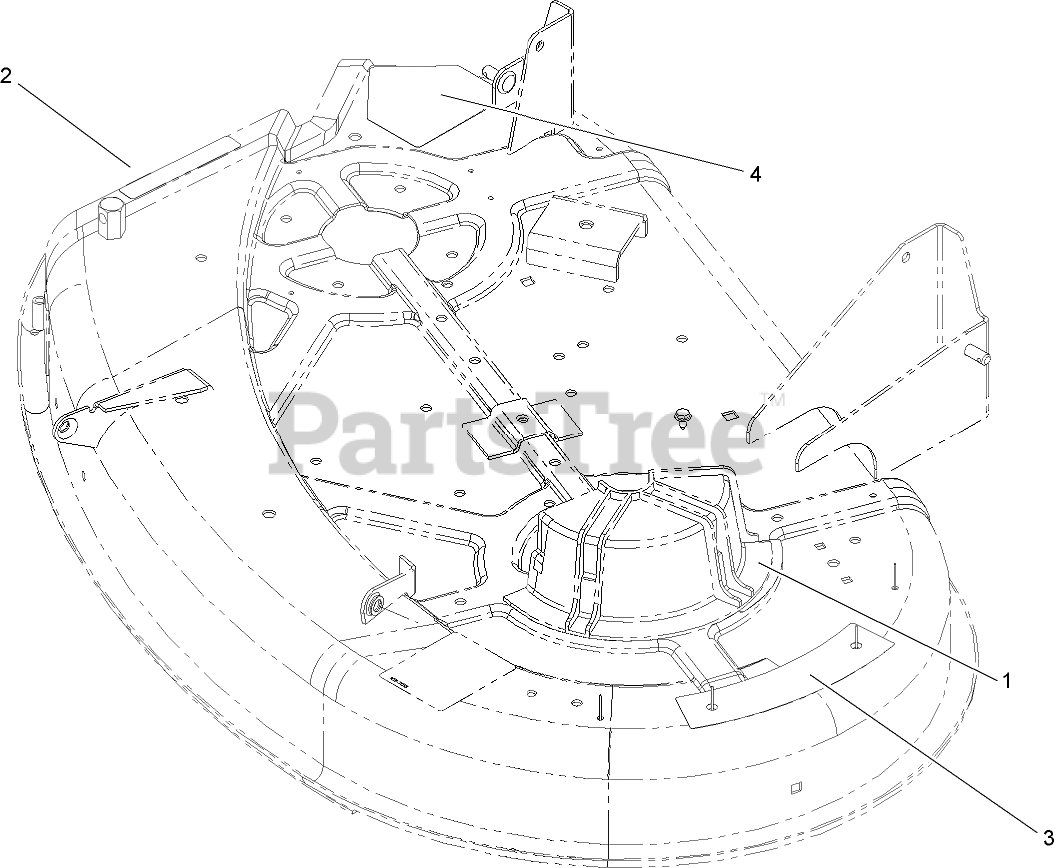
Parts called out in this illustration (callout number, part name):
1	DECAL-DANGER, SHIELD
2	DECAL-DANGER
3	DECAL-DANGER
4	DECAL-DANGER
